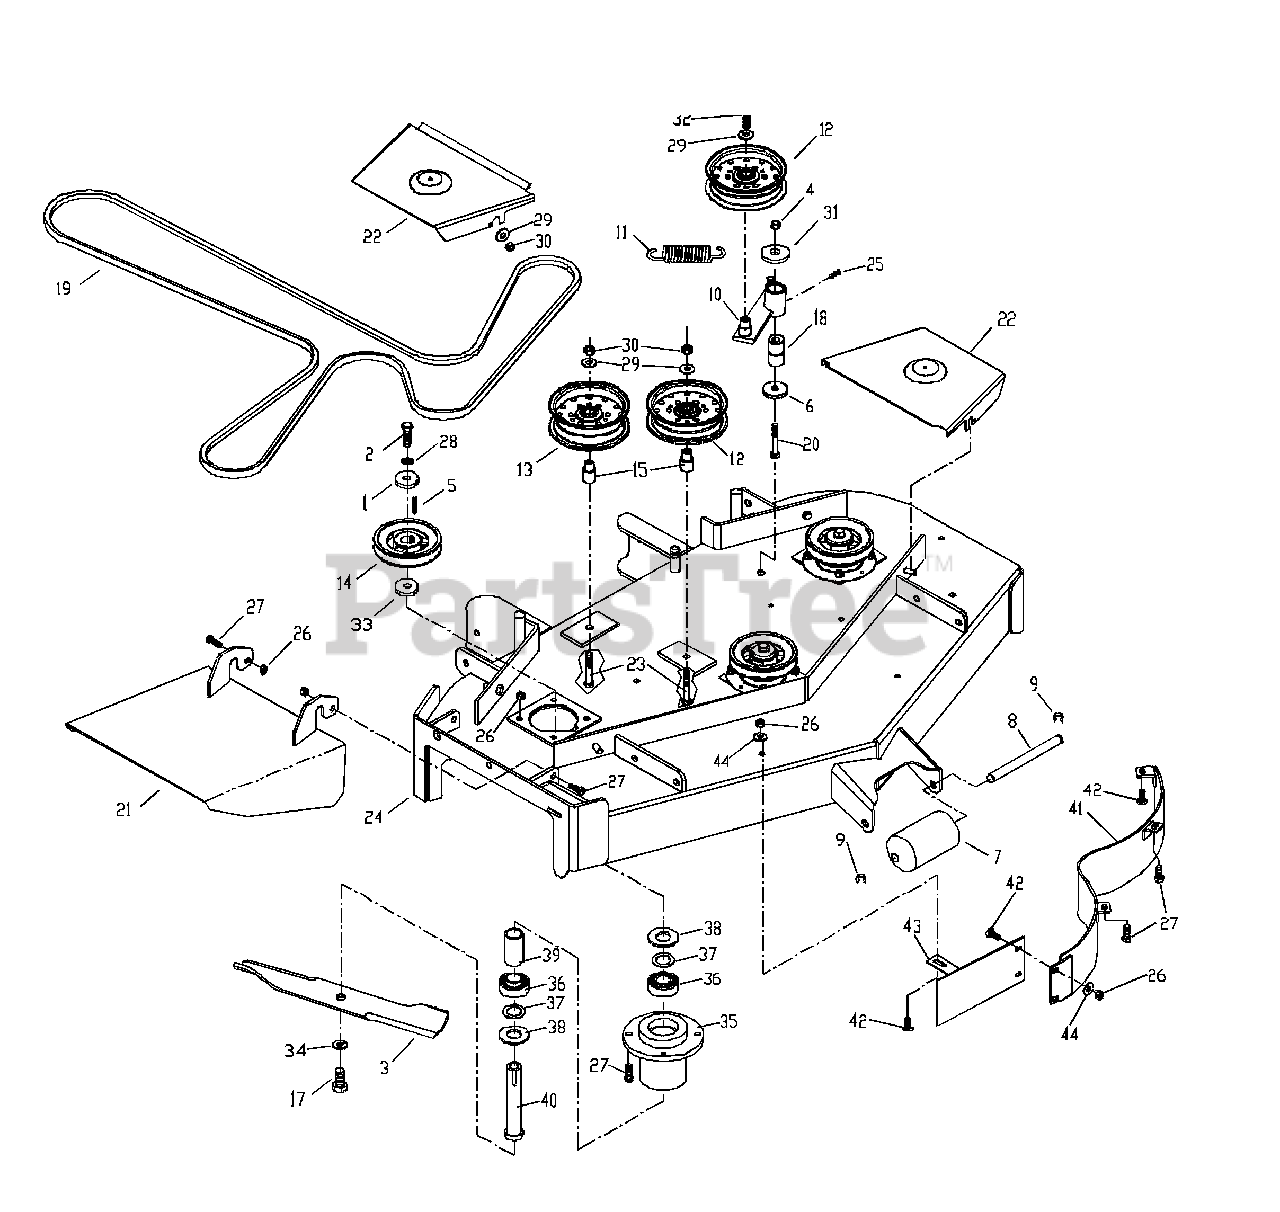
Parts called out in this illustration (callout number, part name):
1	HEAVY WASHER
2	HCS 7/16 X 1.500
3	BLADE 14.875
4	NUT 1/2 NYLOC
5	KEY 1/4 X 1.125
6	SUPPORT WASHER
7	ANTI-SCALP ROLLER
8	ROLLER AXLE
9	E-RING 1/2
12	IDLER PULLEY
13	IDLER PULLEY
15	IDLER BUSHING
16	COMPLETE HOUSING
17	HCS 5/16 X 1.250
18	PIVOT BUSHING
19	BELT
20	HCS 1/2 X 3.250
21	DEFLECTOR CHUTE
22	BELT SHIELD
23	HCS 3/8 X 2.500
24	DECK W/DECALS
25	ZERK
26	NUT 5/16 CTR. LOCK
27	HCS 5/16 X 1.000
28	WASHER 7/16 LOCK
29	WASHER 3/8 FLAT
30	NUT 3/8 CTR. LOCK
31	WASHER 1/2 FLAT
32	HCS 3/8 X 1.00 SERR. HD.
33	MACH. BUSHING
34	WASHER 5/8 LOCK
36	BEARING
37	MACH. BUSHING
38	MACH. BUSHING
41	MAIN BAFFLE
42	RHSNB 5/16 X .625
43	CENTER BAFFLE
44	WASHER 5/16 FLAT
